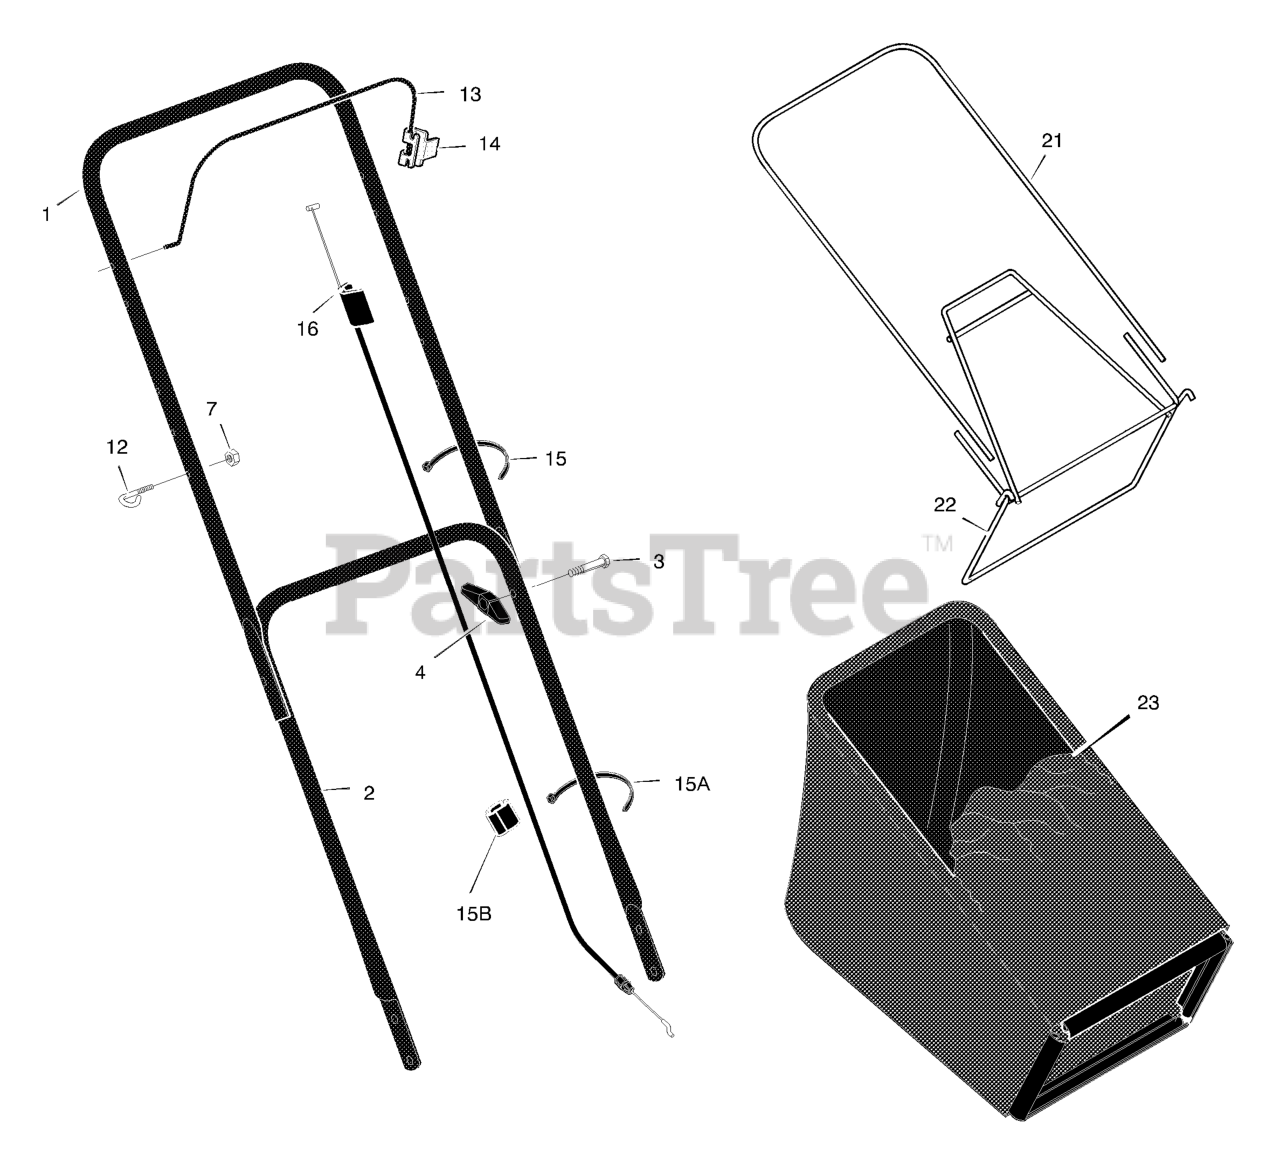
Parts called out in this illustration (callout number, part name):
1	Handle, Upper (Black)
2	Handle, Lower (Black)
4	Knob, Plastic
7	Locknut
12	Guide, Rope
13	Engine Stop Lever
14	Bracket, Stop Lever
15A	Tie, Cable
15B	Fastener, Single Cable
16	Engine Stop Cable
17	Pin, Hair
21	Frame, Top
22	Frame Assembly
23	Bag, Cloth
